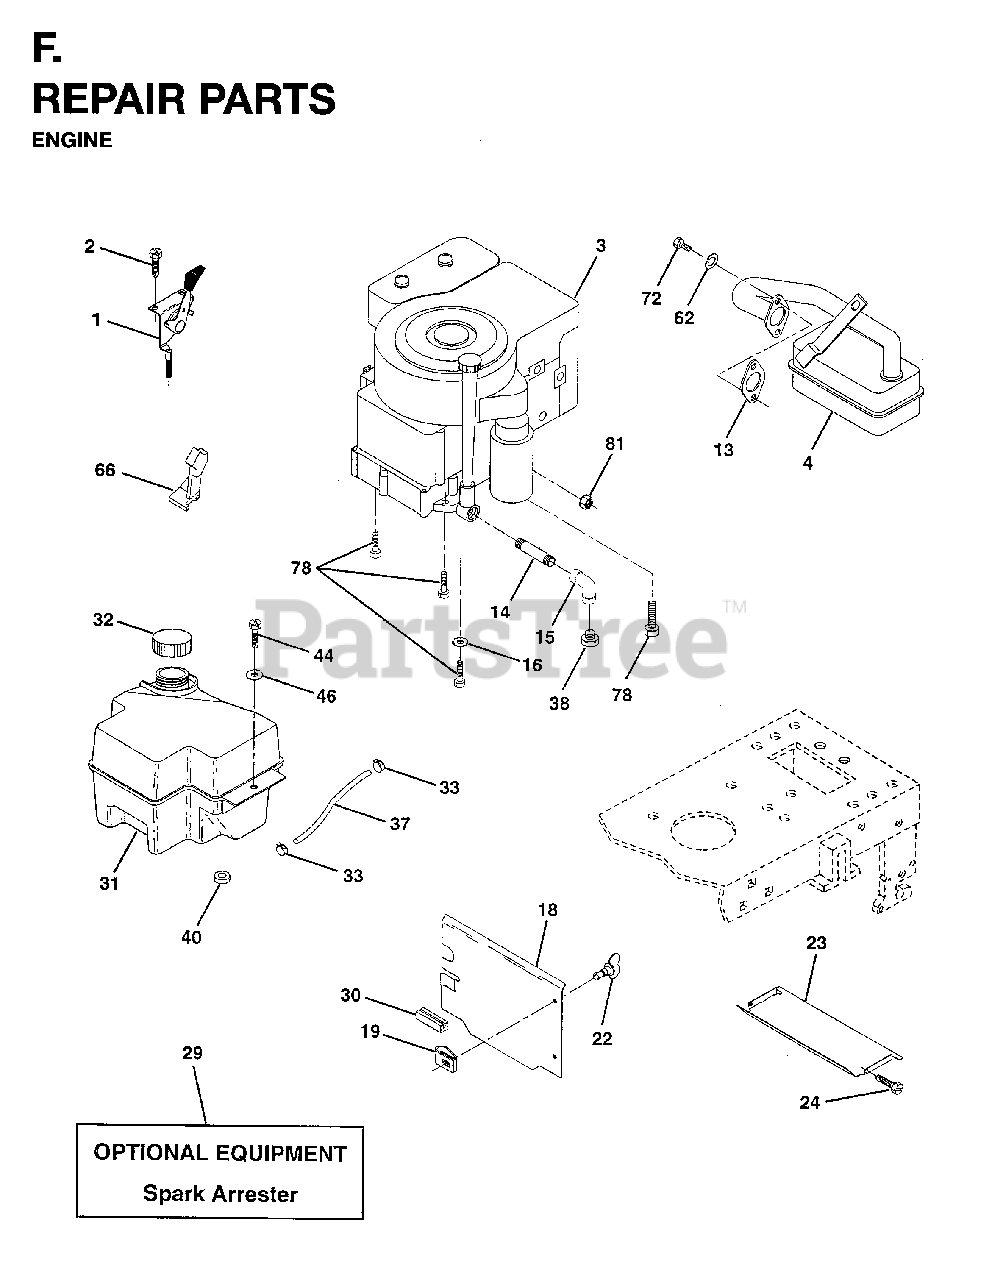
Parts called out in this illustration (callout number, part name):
1	CONTROL
2	BOLT
13	GASKET ENG
15	ELBOW
16	WASHER, LOCK 3/8
18	HEAT SHIELD
19	RECEPTACLE LT
22	STUD 1/4 TURN
23	HEAT SHIELD
29	ARRESTER SPARK (OPTIONAL)
31	FUEL TANK
32	FUEL CAP
33	HOSE CLAMP
37	LINE.FUEL.20
40	SNAP BUSHING T
62	LOCKWASHER
66	STOP THROTTLE
72	SCREW
78	BOLT
81	NUT
